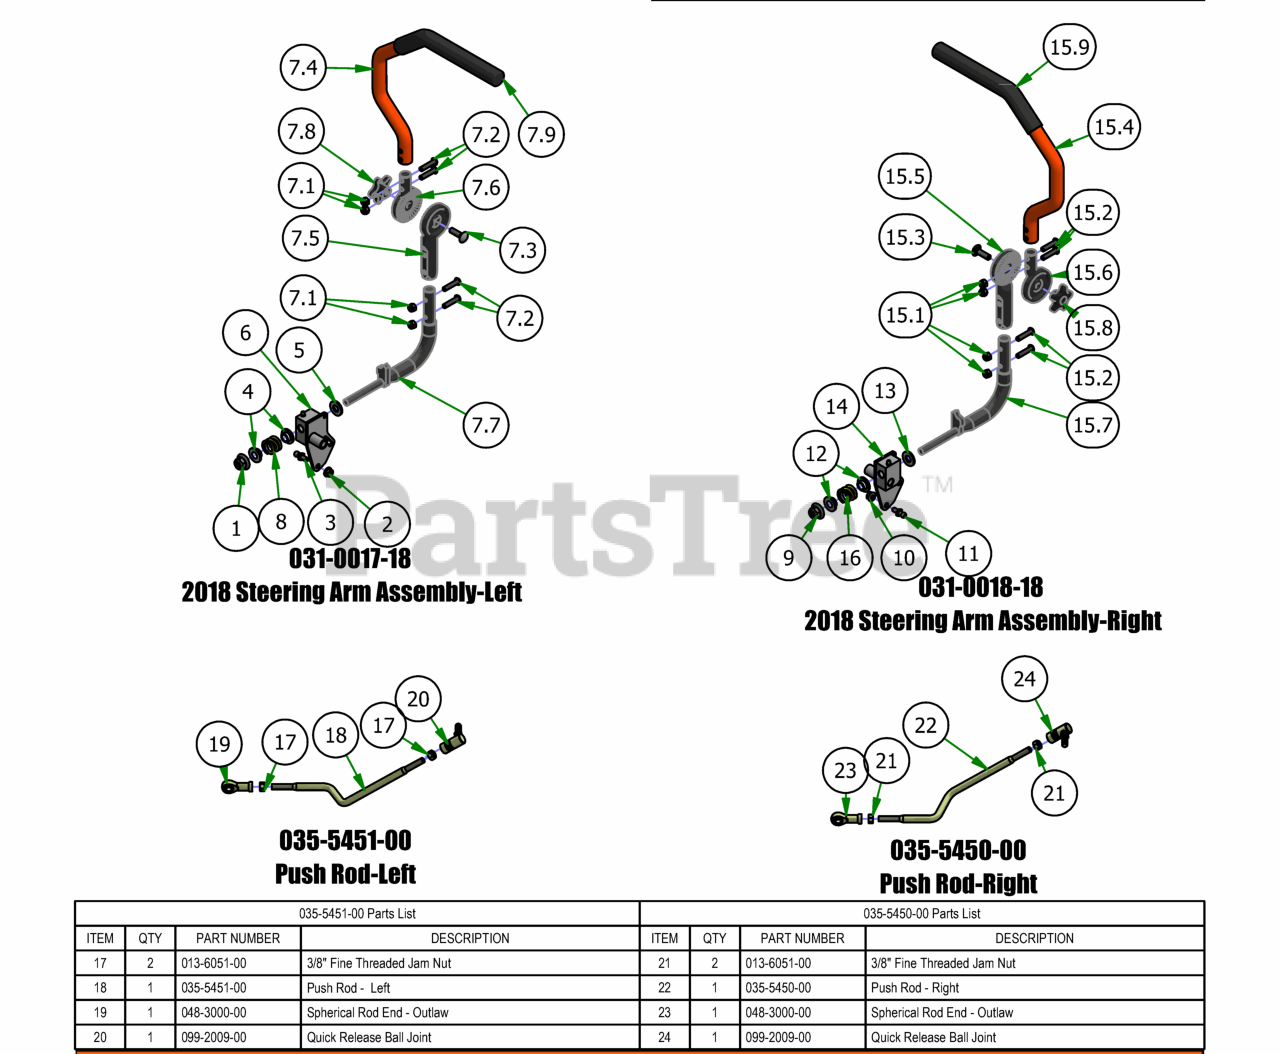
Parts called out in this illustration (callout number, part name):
1	1/2-13 Nylon Flange Nut
2	5/16" Flange Nut
3	10mm Damper Ball Stud-Steering
4	.515 ID Nylon Shoulder Washer
5	.505 Nylon Spacer
6	2017 Drive Lever Housing - Left
7	2018 Adjustable Steering Arm - Left
7.1	5/16-18 Nylock Insert Locknut
7.2	5/16-18 BHCS, TORX DRIVE
7.3	3/8" x 1 1/4" Carriage Bolt
7.4	Upper Tube-Adjustable Steering
7.5	2018 Lower Adjuster - Steering Arm- Left
7.6	2018 Upper Adjuster - Steering Arm- Left
7.7	Steering Arm Elbow (Left)
7.8	Black Knob for Adjustable Steering Arm
7.9	Rubber Grip
8	Drive Lever Spring
9	1/2-13 Nylon Flange Nut
10	5/16" Flange Nut
11	10mm Damper Ball Stud-Steering
12	.515 ID Nylon Shoulder Washer
13	.505 Nylon Spacer
14	2017 Drive Lever Housing - Right
15	2018 Adjustable Steering Arm - Right
15.1	5/16-18 Nylock Insert Locknut
15.2	5/16-18 BHCS, TORX DRIVE
15.3	3/8" x 1 1/4" Carriage Bolt
15.4	Upper Tube-Adjustable Steering
15.5	2018 Lower Adjuster - Steering Arm- Right
15.6	2018 Upper Adjuster - Steering Arm- Right
15.7	Steering Arm Elbow (Right)
15.8	Black Knob for Adjustable Steering Arm
15.9	Rubber Grip
16	Drive Lever Spring
17	3/8" Fine Threaded Jam Nut
18	Push Rod - Left
19	Spherical Rod End - Outlaw
20	Quick Release Ball Joint
21	3/8" Fine Threaded Jam Nut
22	Push Rod - Right
23	Spherical Rod End - Outlaw
24	Quick Release Ball Joint
